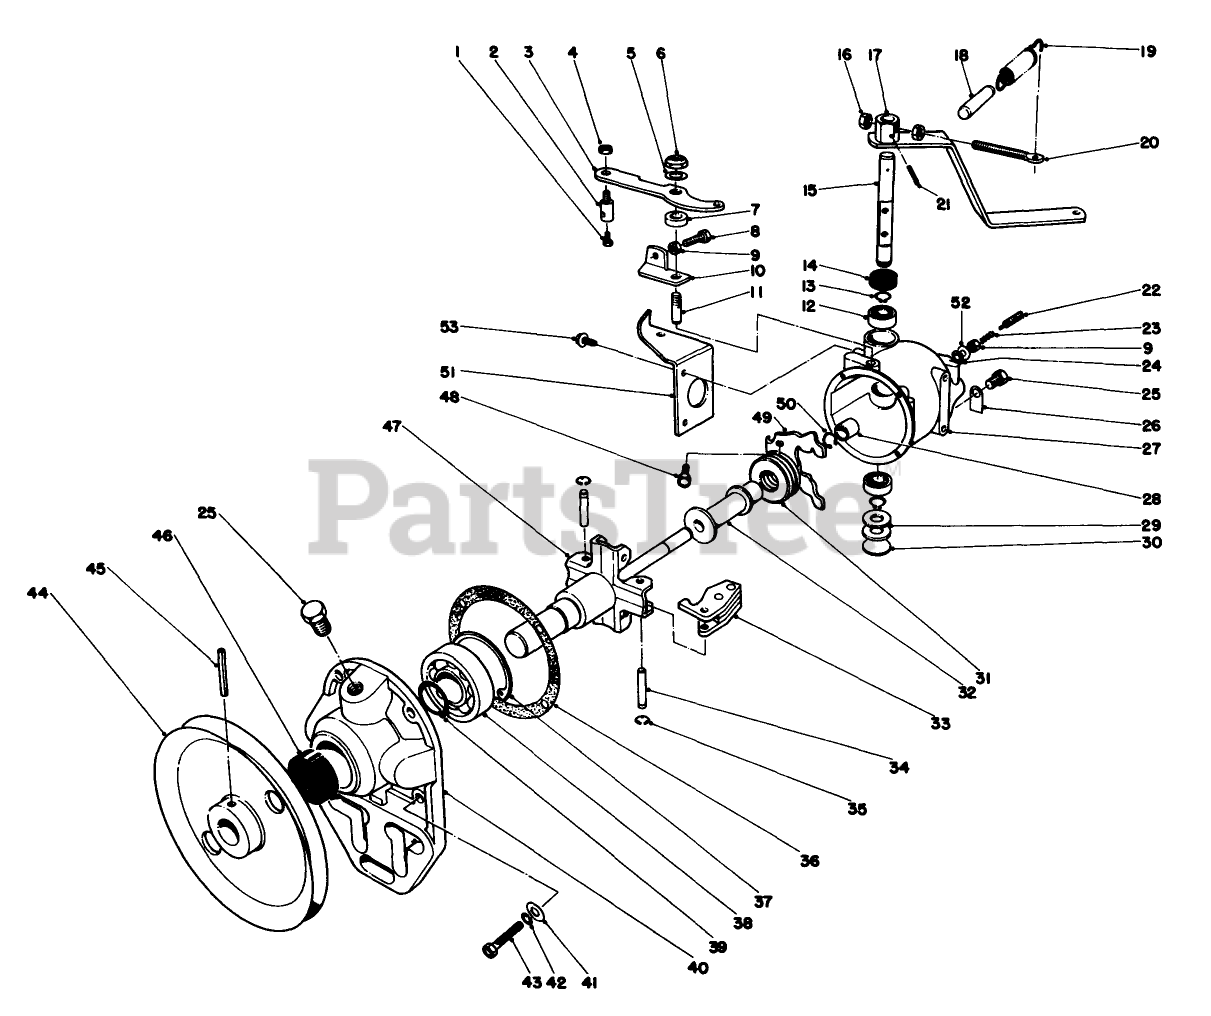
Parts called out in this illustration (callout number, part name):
1	SCREW-HH
2	SWIVEL
3	Speed Change Lever
4	NUT-LOCK, NI
5	WASHER
6	STOP NUT
7	Spacer
8	SCREW-HH
9	NUT-HEX
10	Stop Bracket
12	BALL BRG
13	EXT SNAP RING
14	OIL SEAL
15	Rocker Shaft
16	NUT-HEX
17	THROTTLE LEVER ASM
18	FORCED IDLE PLUG
19	SPRING
20	EYESCREW
21	PIN-ROLL
22	BUMPER SCREW
23	BUMPER SPRING
24	SEALING WASHER
25	PIPE PLUG
26	OIL LEVEL TAG
28	DRIVE SHAFT BUSHING
29	WASHER
30	WELCH PLUG
31	Thrust Bearing
32	Thrust Sleeve
33	WEIGHT ASM
34	Weight Pin
35	E RETAINING RING
36	GASKET
37	INT BEVELED
38	BEARING-BALL
39	RETAINING RING
40	FLANGE
41	WASHER-FLAT
42	WASHER-LOCK
43	10-24 X 7/8 IND HD SC
44	Pulley
45	PIN-SPRING
46	OIL SEAL
47	SPIDER & SHAFT ASM
48	MACHINE SCREW
50	RETAINING RING
51	Bracket
52	Shim Washer
53	SCREW
